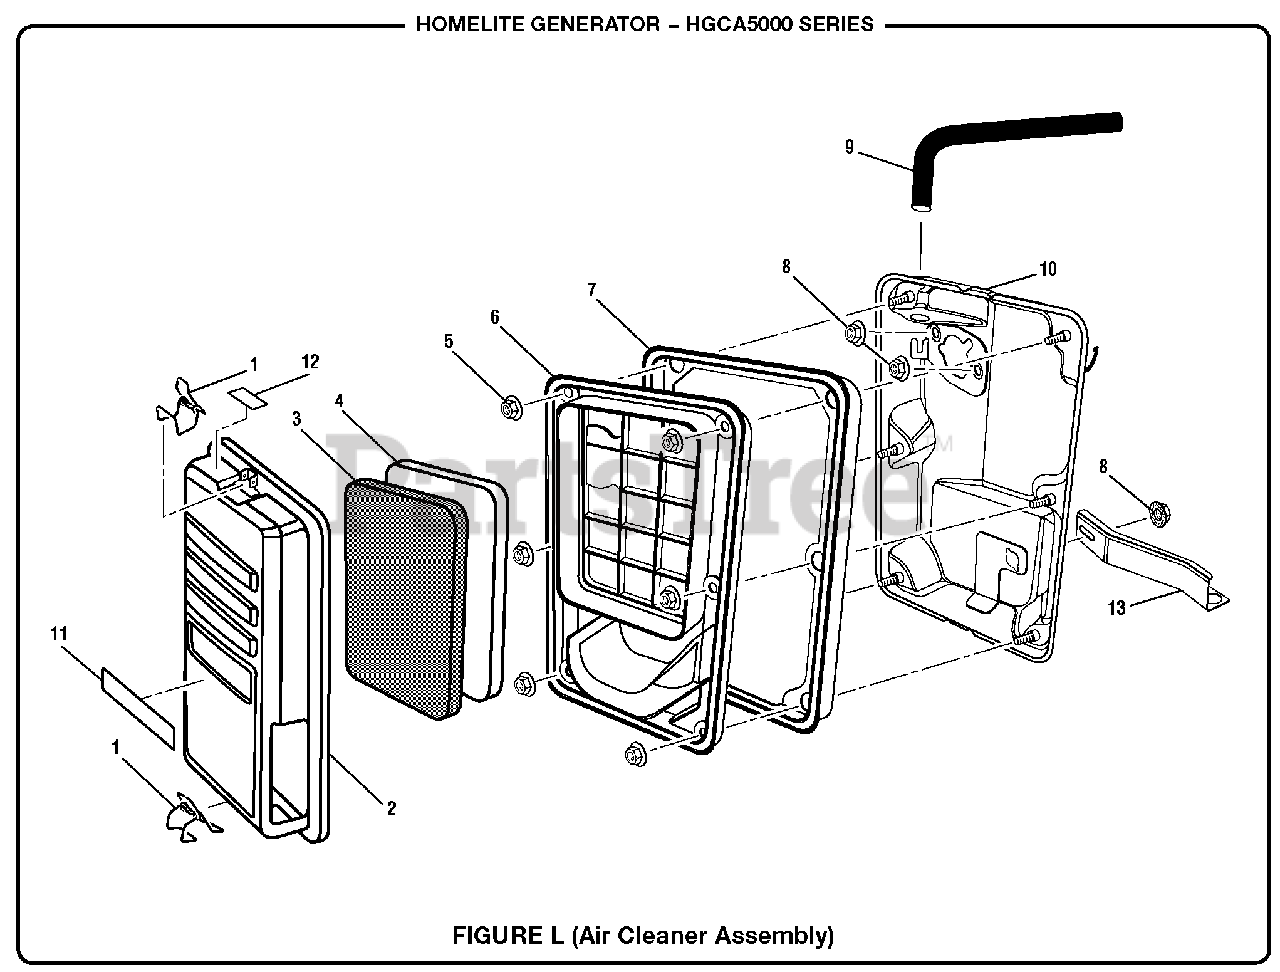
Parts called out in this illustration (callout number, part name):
1	Air Cleaner Cover Hinge
2	Air Cleaner Cover Assembly (Incl. Key No. 1)
3	Pre-filter
4	Air Filter Element
5	Nut (M5, Flange Nut)
6	Filter Element Retainer
7	Air Cleaner Gasket
8	Nut (M6, Flange Nut)
9	Breather Tube
10	Air Cleaner Support
11	Starting Instruction Label
12	Choke Label
13	Air Cleaner Bracket
